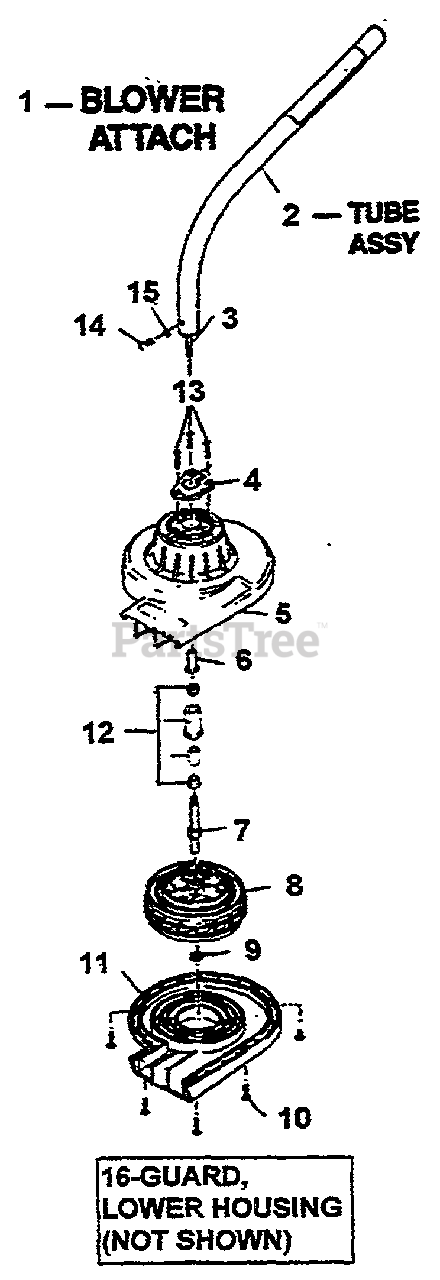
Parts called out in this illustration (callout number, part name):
2	TUBE ASSY
3	FLEX CABLE
5	UPPER HOUSING
6	ARBOR ADAPTER
7	ARBOR SHAFT
8	IMPELLER
10	SCREW
11	LOWER HOUSING
12	ARBOR BUSHING ASSY
13	SCREW
16	GUARD, LOWER HOUSING
